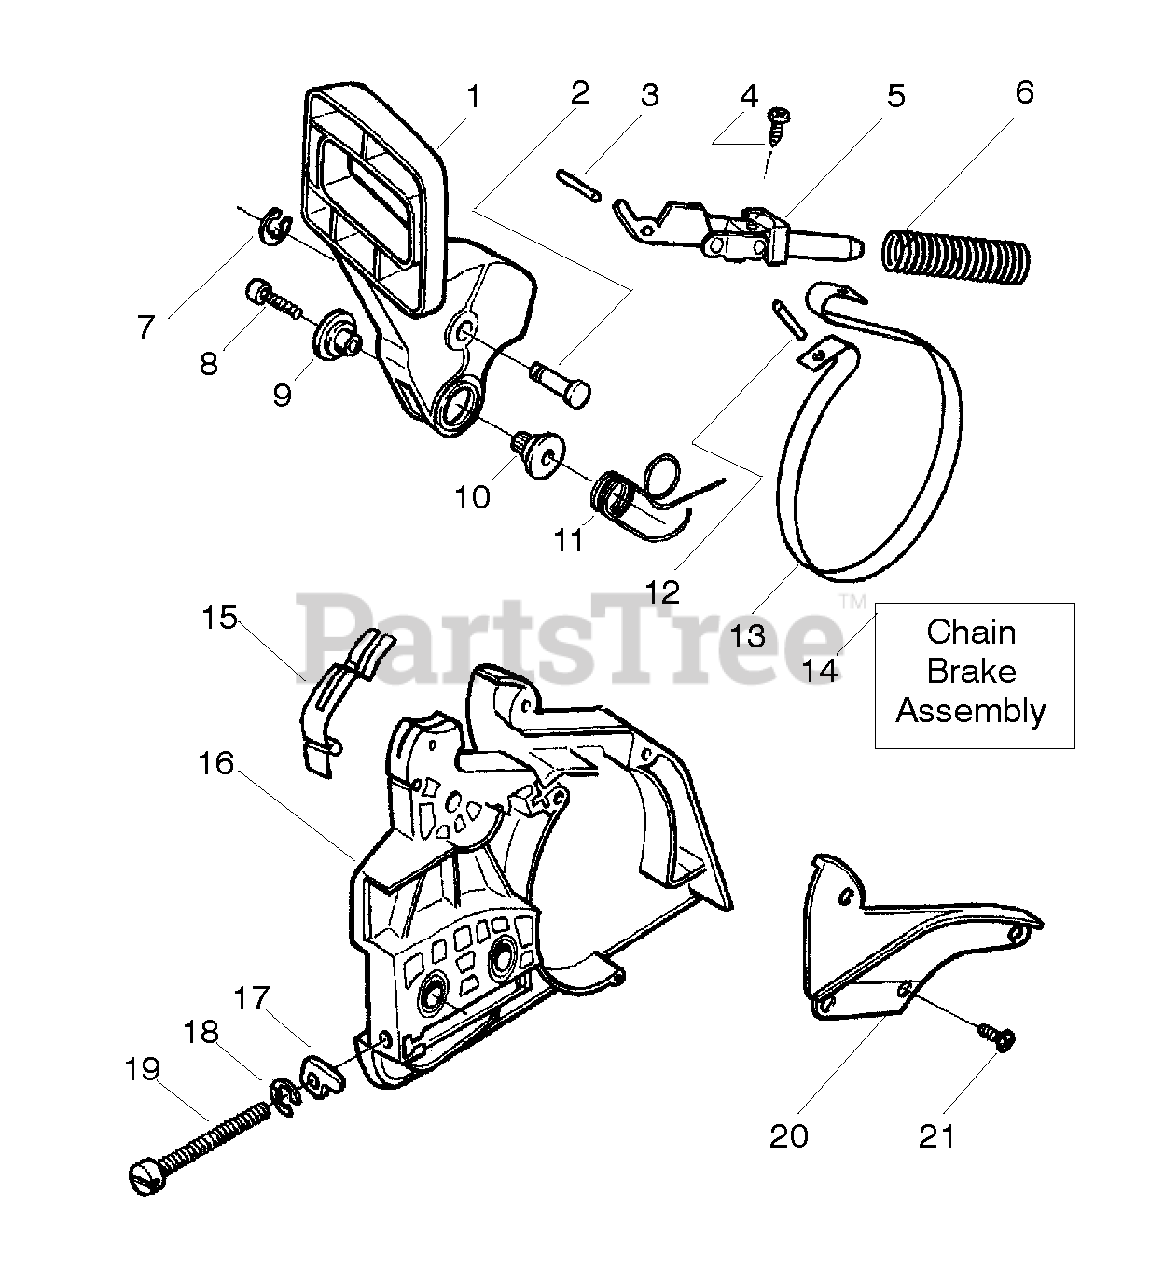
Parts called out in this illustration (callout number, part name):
1	Kit- Lever & Link Assy.
4	Screw
5	Assy-Front Link
6	Spring-Chain Brake
9	Journal-Right
10	Journal-Left
11	Spring-Handguard
12	Pin-Spring
13	Band-Brake
14	Assy-Chain Brake
15	Spring-Position
16	Cover-Clutch
17	Pin-Bar Adjusting
19	Screw-Bar Adjusting
20	Cover-Chain Brake Spring
21	Screw
